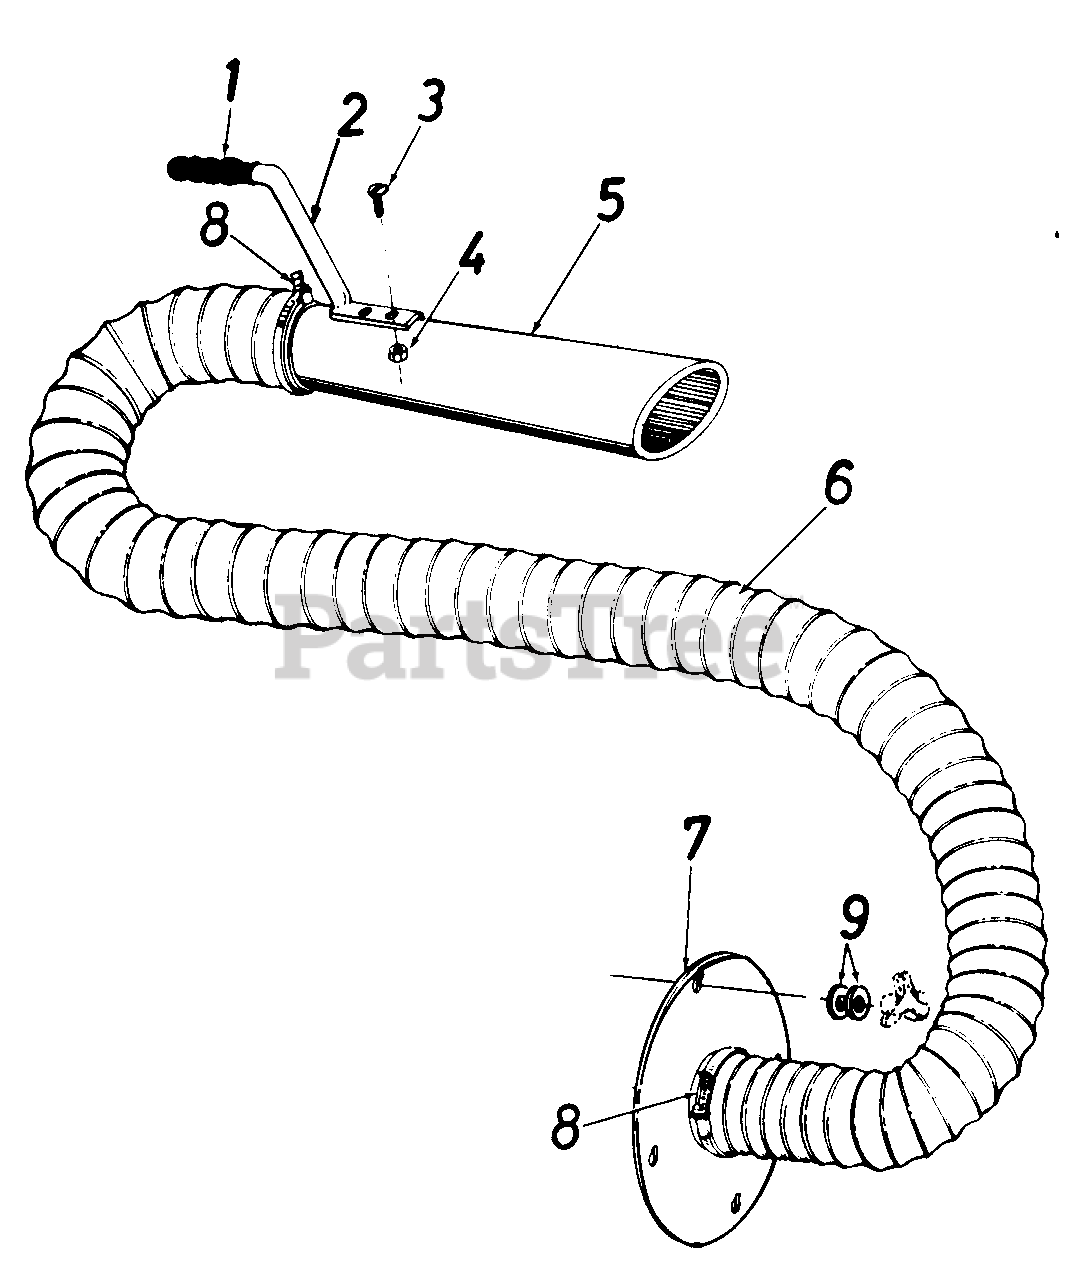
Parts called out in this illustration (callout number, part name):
1	GRIP-BLACK
2	HANDLE-HOSE NOZ LONG
3	SCREW-TRUSS SEMS #10-24 X .50
5	NOZZLE-HOSE
6	HOSE-4IN DIA X 10FT
9	WASHER-FL-.312 X 1.125 X .125
